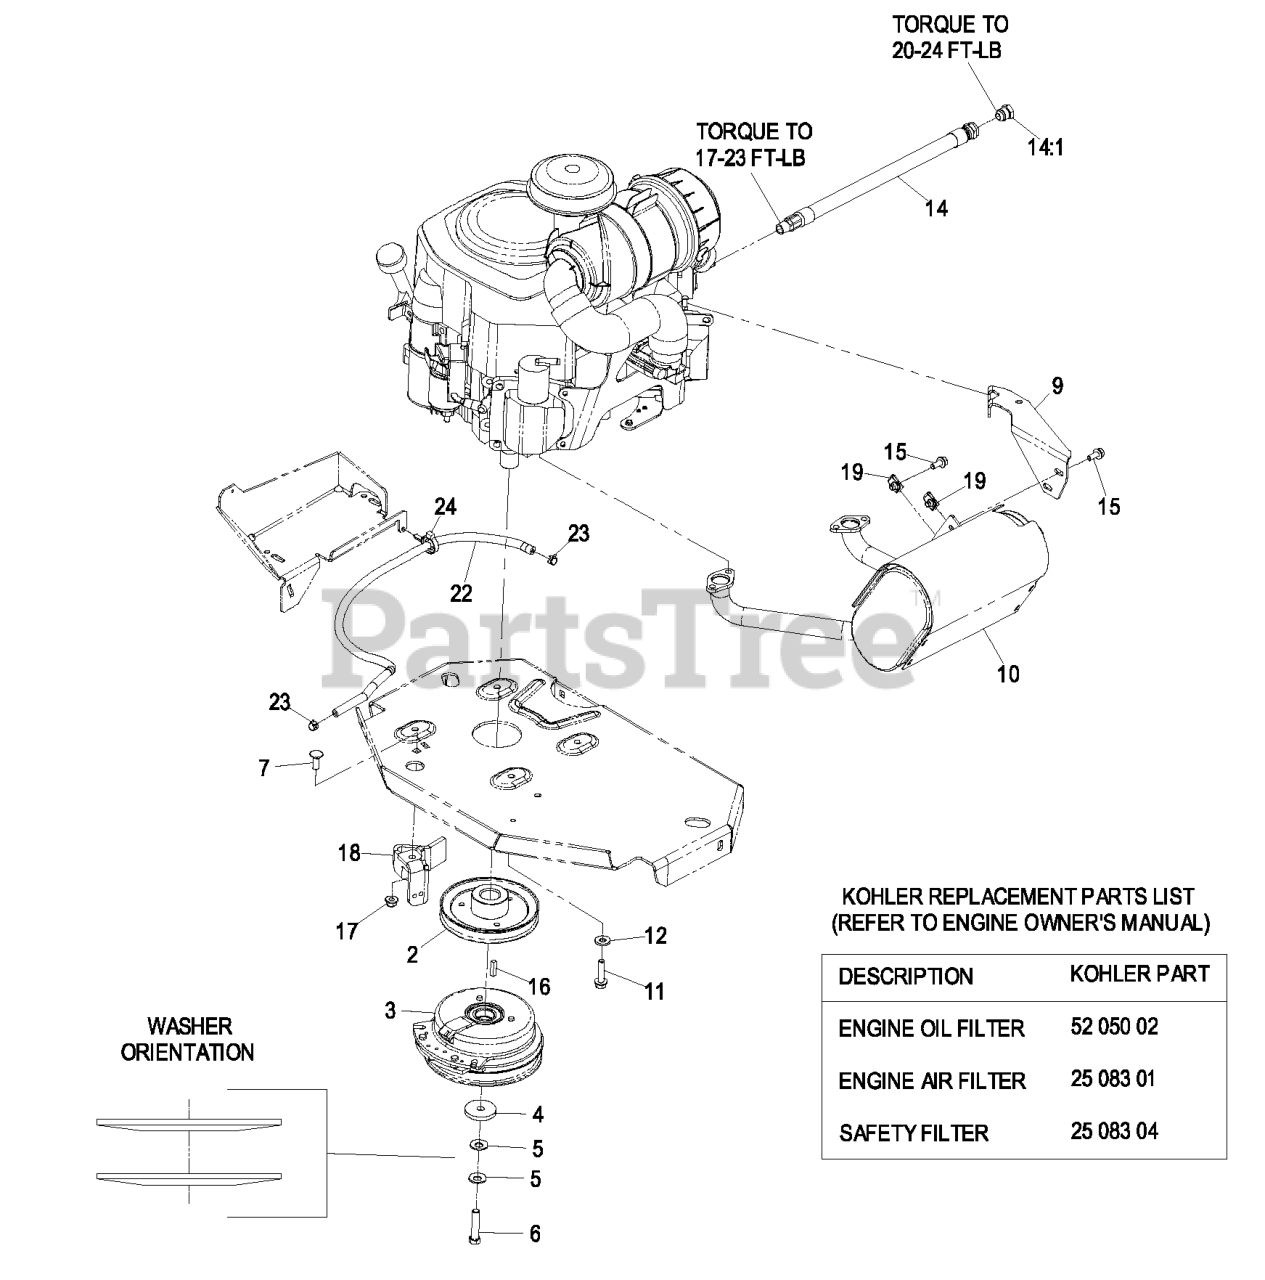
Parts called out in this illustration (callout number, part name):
2	SHEAVE
3	CLUTCH KIT
4	WASHER-CLUTCH
5	WASHER-SPRING
6	SCREW-HH W/LOCTITE
7	SCREW-CARR
11	SCREW-HWH
12	WASHER-BELLEVILLE
15	SCREW-HHF
17	NUT-HF, NI
18	CLUTCH-ANCHOR
22	HOSE-FUEL
23	CLAMP-HOSE
24	CLAMP-HOSE
27	WASHER-SPRING
28	SCREW-HH
